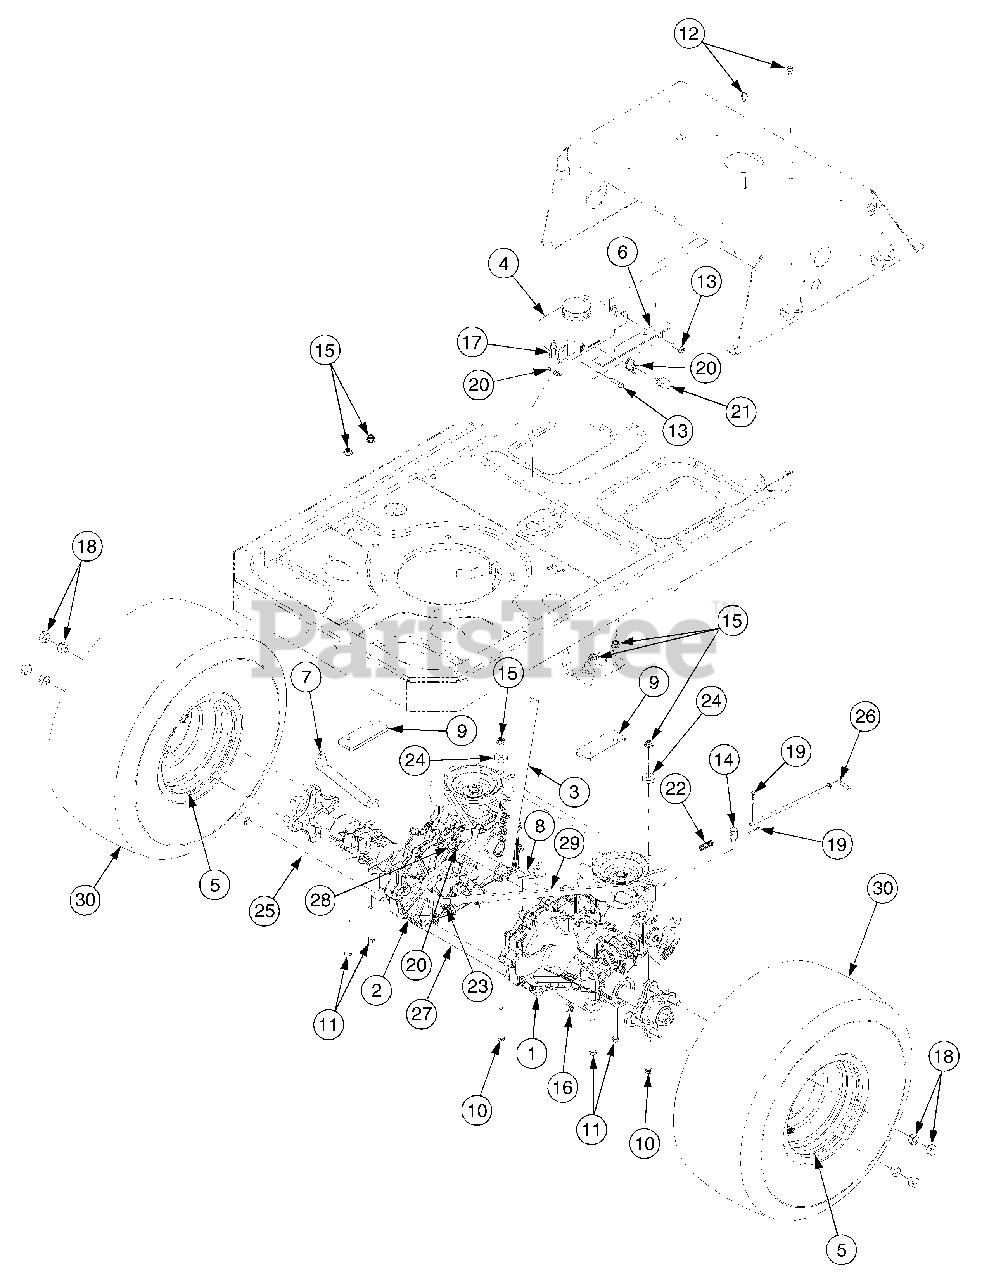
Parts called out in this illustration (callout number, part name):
1	Transmission Assembly, RH
2	Transmission Assembly, LH
3	Breather Assembly
4	Tank, Expansion
11	Screw, Hex Cap, 5/16-18 x 3.0 GR5
12	Screw, Hex Washer Head Tapp, 1/4-20 x .5
13	Screw, Hex Washer Head Tapp, 1/4-20 x 1.0
15	Nut, Hx Flnge Insert Lck, 5/16-18 GrF
16	Nut, Hx Flnge Insert Lck, 3/6-16 GrF
17	Nut, Speed, 1/4-20
18	Nut, Lug, 7/16-14
19	Pin, Internal Cotter
20	Clamp, Hose
21	Cap, 1/2" ID
22	Spring, Compression, .405 x 1.17 ...
23	Spring, Extension
24	Washer, Flat, .35 x 1.0 x .25
25	Rod, .337 x 14.75
26	Rod, Bypass
27	Tube, 7/16 x 3/4 x 11.3
28	Fitting, Straight, 9/16 x 1/2
29	V-Belt, Type A Sec x 57.7
